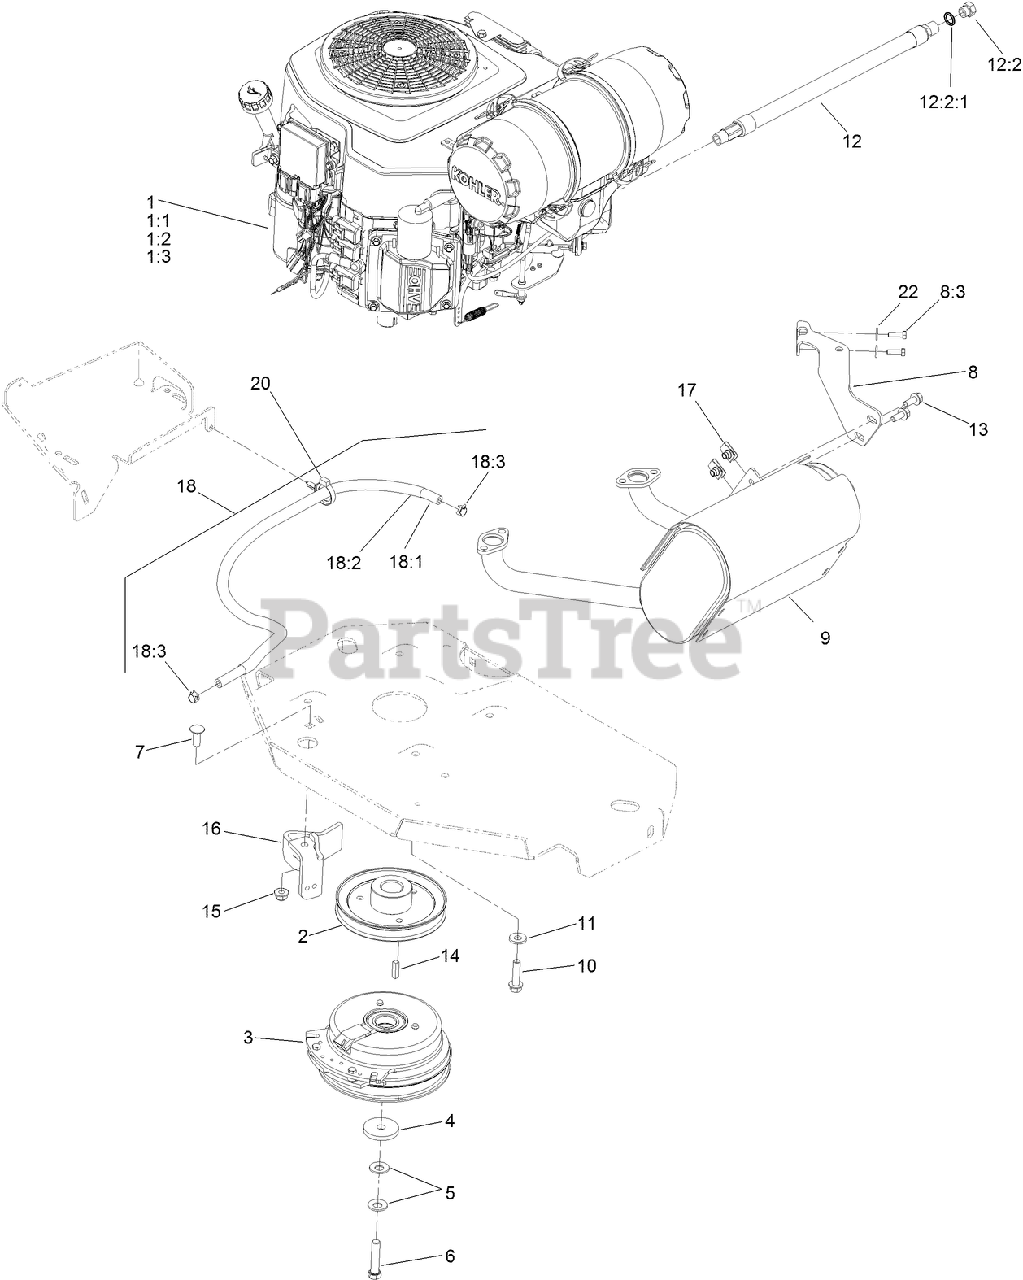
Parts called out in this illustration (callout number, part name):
1:1	KOHLER 52 050 02-S ENGINE OIL FILTER
1:2	KOHLER 25 083 01-S ENGINE AIR FILTER
1:3	KOHLER 25 083 04-S SAFETY FILTER
2	SHEAVE
3	CLUTCH KIT
4	WASHER-CLUTCH
5	WASHER-SPRING
6	SCREW-HH
7	SCREW-CARR
8	BRACKET-MUFFLER
8	MUFFLER BRACKET KIT
8:3	SCREW-HH
9	MUFFLER--KIT
10	SCREW-HWH
11	WASHER-BELLEVILLE
12	OIL DRAIN HOSE ASM
12:2	PLUG-HH
12:2:1	O-RING
13	SCREW-HHF
15	NUT-HF, NI
16	CLUTCH-ANCHOR
17	NUT-U
18	FUEL LINE ASM
18:1	HOSE-FUEL
18:2	SLEEVE-THERMAL
18:3	CLAMP-HOSE
20	CLAMP-HOSE
22	WASHER-SPRING
